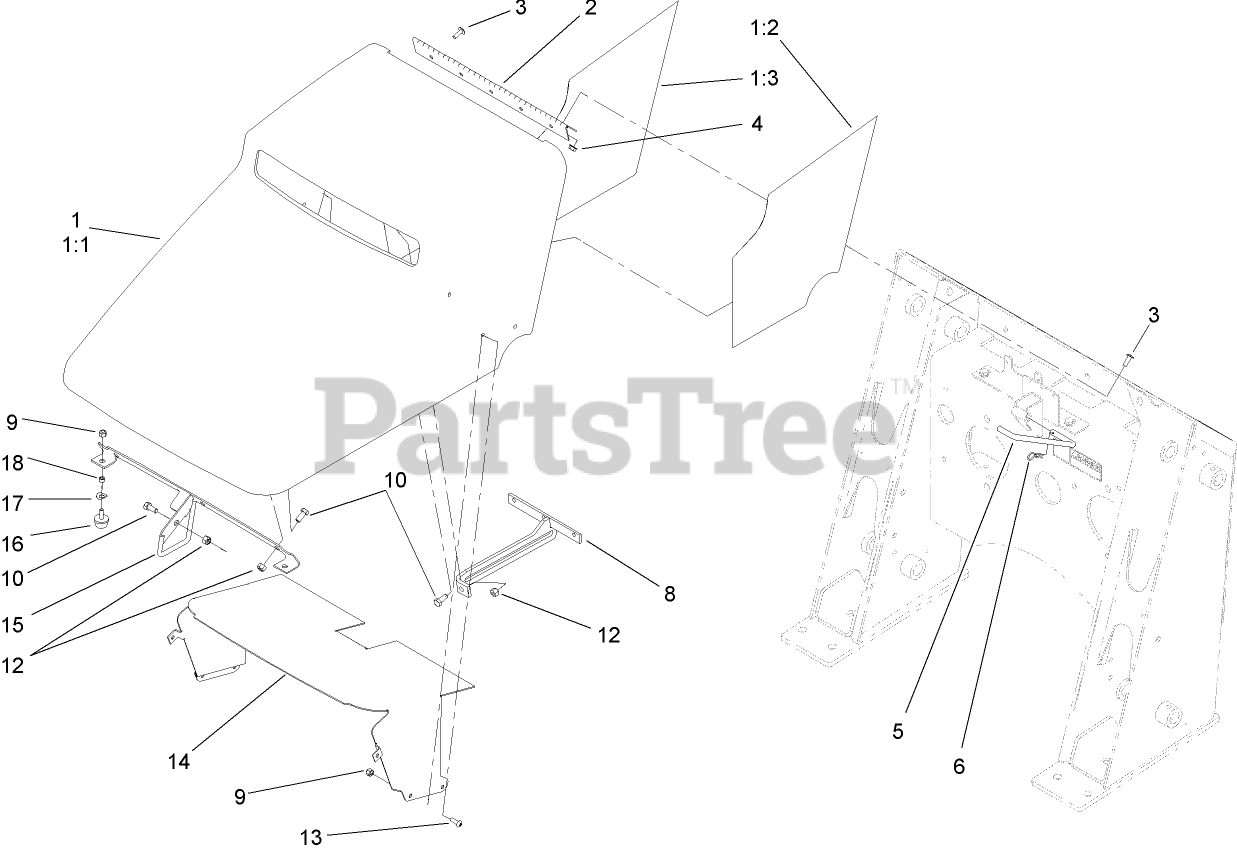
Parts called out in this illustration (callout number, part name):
1	HOOD ASM
1:1	DIESEL HOOD ASM
1:2	FOILTAPE-LH
1:3	FOILTAPE-RH
2	HINGE-HOOD
3	SCREW-HEAD, TRUSS
4	NUT-HF
5	ROD-SUPPORT, HOOD
6	PIN-COTTER
8	PROP ROD BRACKET ASM
9	NUT-LOCK, NI
10	SCREW-HH
12	NUT-LOCK, NI
13	SCREW-PRH
14	BAFFLE-HOOD
15	ROD LATCH ASM
16	BUMPER
17	WASHER-SPRING
18	SPACER
